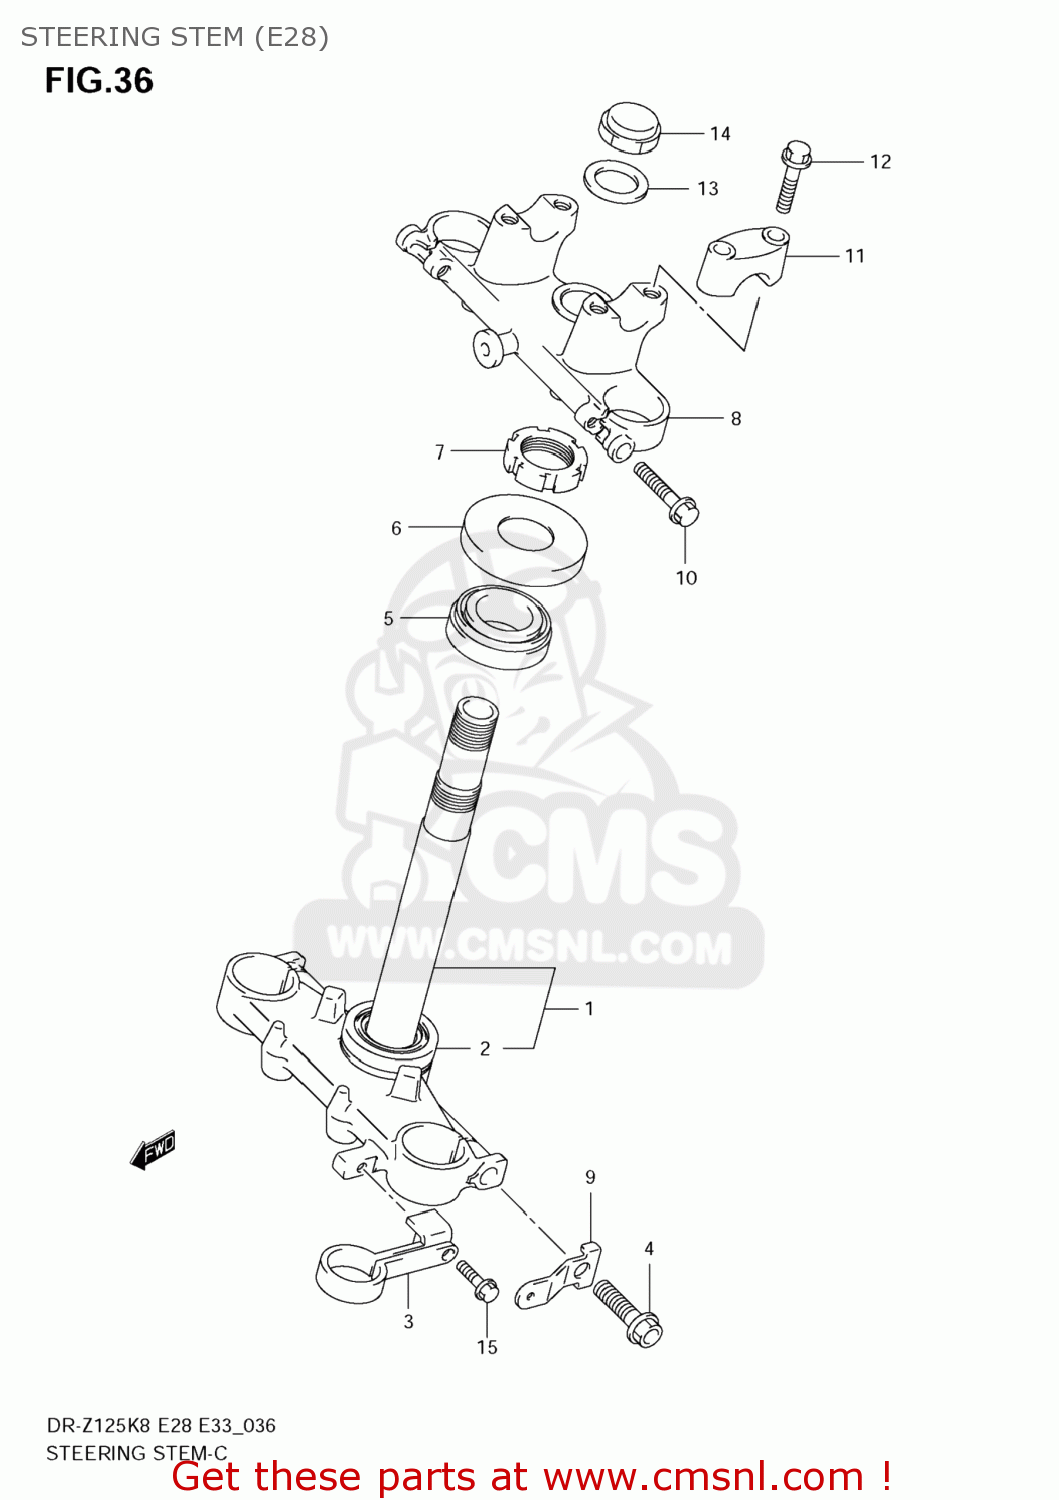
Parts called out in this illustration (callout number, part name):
1	STEM,STEERING
2	BEARING(26X47X15)
3	GUIDE,FR BRAKE HOSE
4	BOLT
5	BEARING(25X47X15)
6	SEAL,STEERING UPR DUST
7	NUT,STEERING
8	BRACKET,UPR
9	BRACKET,FR SIDE RR
10	BOLT
11	HOLDER,HANDLE
12	BOLT
13	WASHER
14	NUT
15	BOLT
